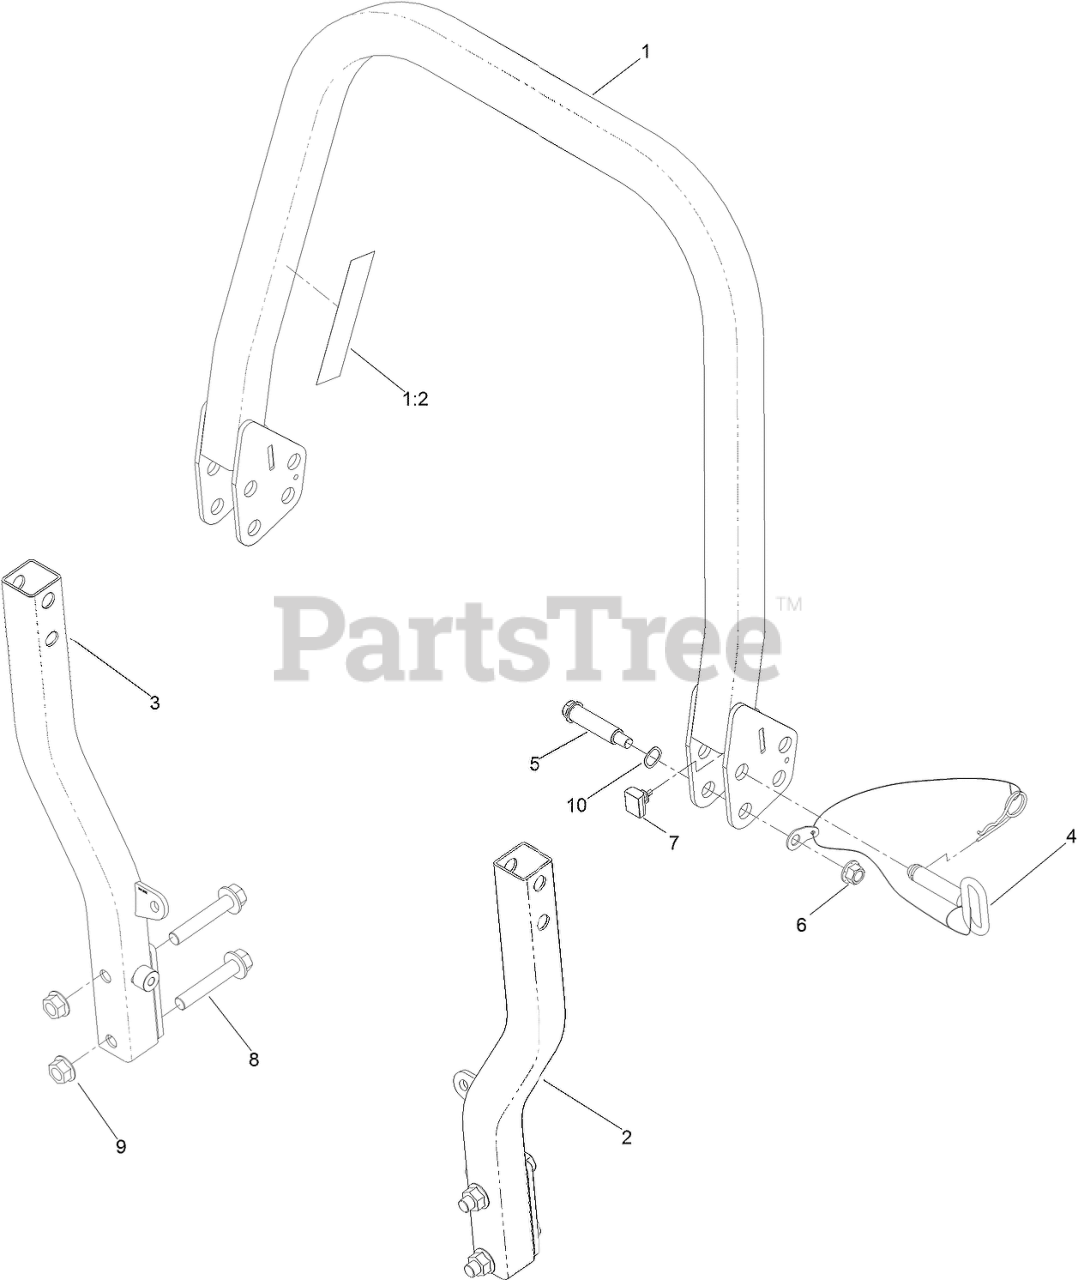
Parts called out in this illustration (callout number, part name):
1	UPPER ROPS ASM
1:2	DECAL-WARNING
2	LH LOWER ROPS ASM
3	RH LOWER ROPS ASM
4	PIN-FOLD, ROPS
5	BOLT-SHOULDER
6	NUT-LOCK
7	BUMPER-ROPS
8	SCREW-HHF
9	NUT-FLANGE
10	WASHER-WAVE
